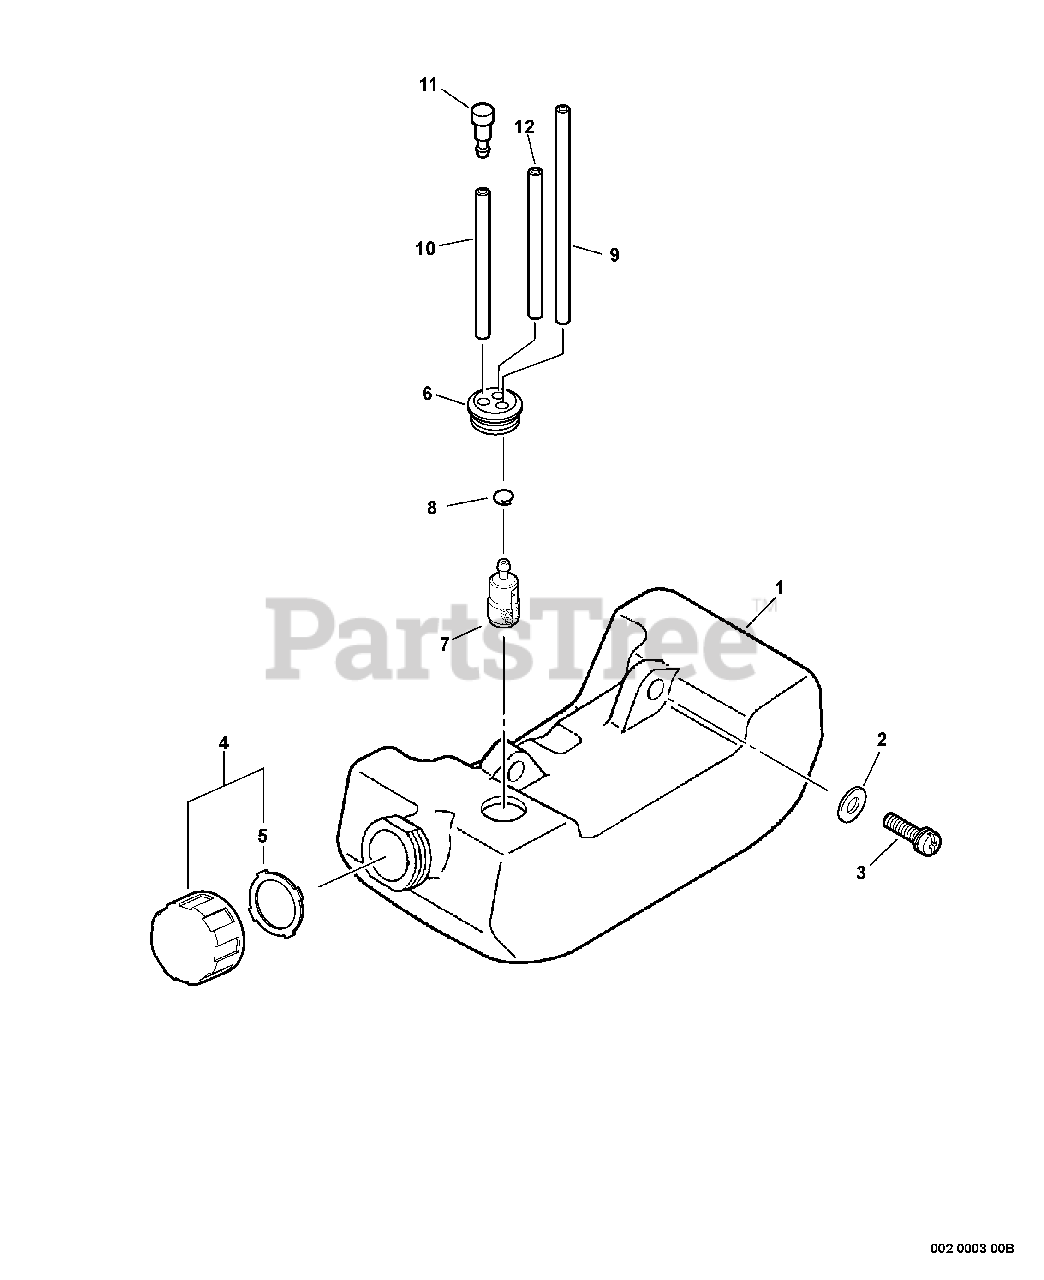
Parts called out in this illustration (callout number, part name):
1	TANK, FUEL
2	WASHER - 5
3	SCREW - 5X16
4	CAP ASSY
5	GASKET, CAP
6	GROMMET
7	FILTER, FUEL
8	CLIP - 6
9	PIPE - 3X5X180 -- BLACK
10	PIPE - 3X5X70 -- BLACK
11	VENT, FUEL TANK
12	PIPE - 3X6X90 -- CLEAR
